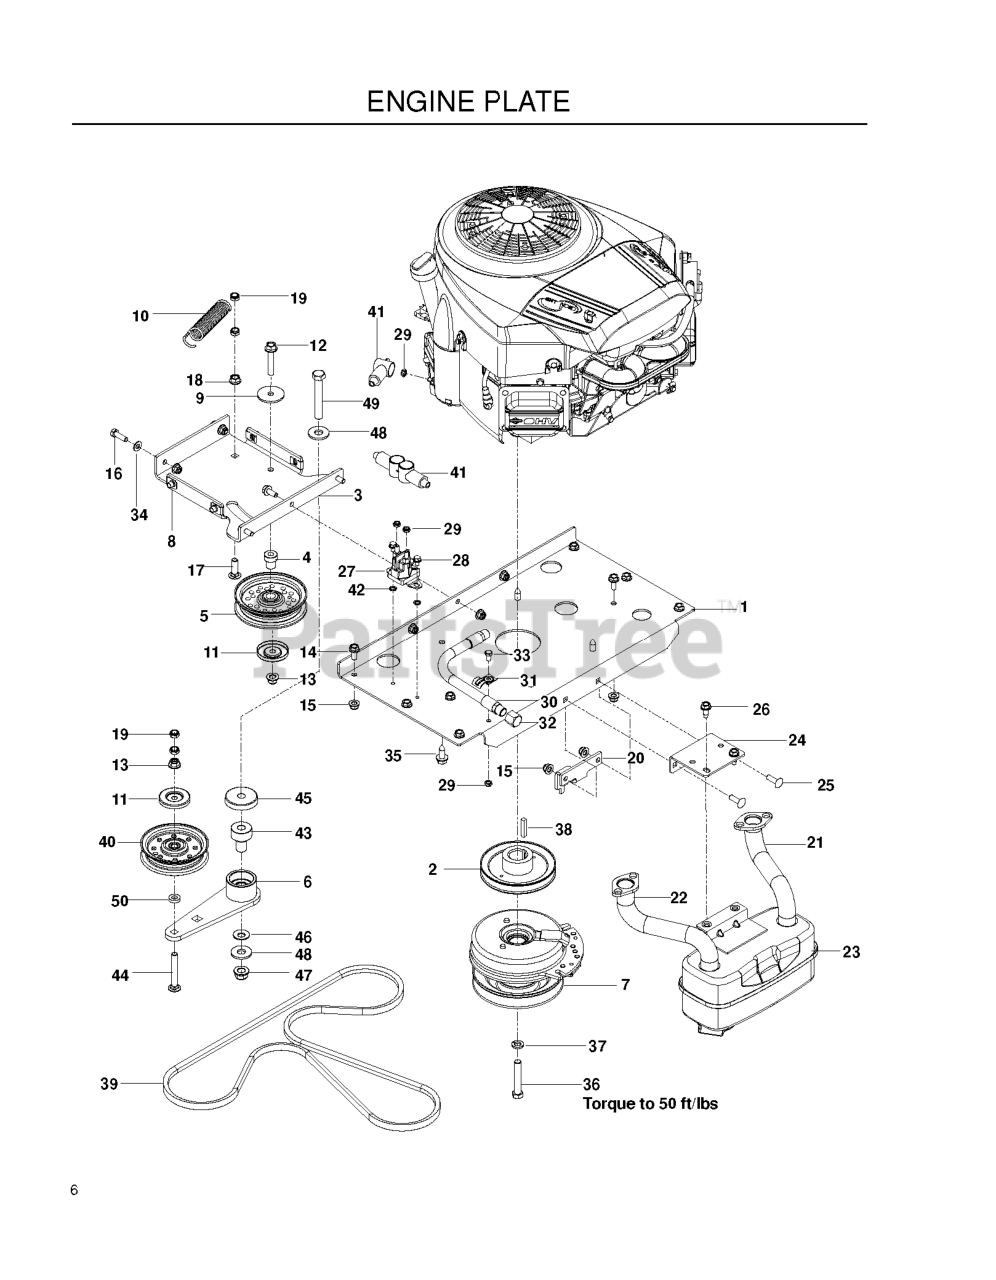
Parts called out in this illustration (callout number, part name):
1	PLATE, ENGINE W/DECALS
2	PULLEY, V, 1.125 BORE
3	PLATE, IDLER, BLK
4	PIVOT, IDLER
5	IDLER PULLEY
6	ARM, IDLER, STEEL, W/BGS
7	OGURA GT2.5 CLUTCH
8	U-CLIP 5/16-18 NUT RETAINER
9	WASHER, 3/8 SPEC
10	SPRING, PUMP
11	DUST SHIELD
12	HHFS 3/8-16 X 2.0 GD 5
13	NUT 3/8-16 HEX FLG NYLOC ZD
14	HHFS 5/16-18 X 3/4
15	5/16-18 NYLOC FLANGE NUT
16	HCS 5/16C X 1
17	RHSNB 3/8-16 X 1-1/4
18	NUT 3/8C WHIZ
19	NUT HEX 3/8-16 NYLON, THIN
20	STOP, CLUTCH, BLACK
21	RP.EXHAUST.TUBE.LH.BS/TWIN
22	EXHAUST.TUBE.RH.BS/TWIN
23	MUFFLER ASM TWIN
24	BRKT, MUFFLER, BLK
25	RHSSNB 5/16C X 1.0
26	BOLT 5/16-18 X 3/4
28	HWST 1/4C X 3/8
29	JAM NUT 1/4C (2 2 PW01)
30	OIL DRAIN HOSE
33	HCS 1/4-20.
34	FLAT WASHER 5/16 SAE
35	HHFS 3/8-16 X 1.0 THD FORMING
36	BOLT 7/16F X 2 1/2
37	WASHER 7/16 LOCK
38	KEY, 1/4 SQ X 1 1/4
39	BELT, HYDRO, 3400
40	FLAT IDLER PULLEY
42	WASHER 1/4 INT TOOTH
43	PIVOT, BEARING
44	RHSNB 3/8-16 X 2.75
45	SHIELD, DUST
46	CONTACT BELLSPR 1/2
47	NUT, 1/2-13 HEX FLG NYLOC ZD
48	WASH USS FLAT 1/2
49	HCS 1/2C X 3 1/4
50	WASHER 3/8 X 3/4 X .187 TK
